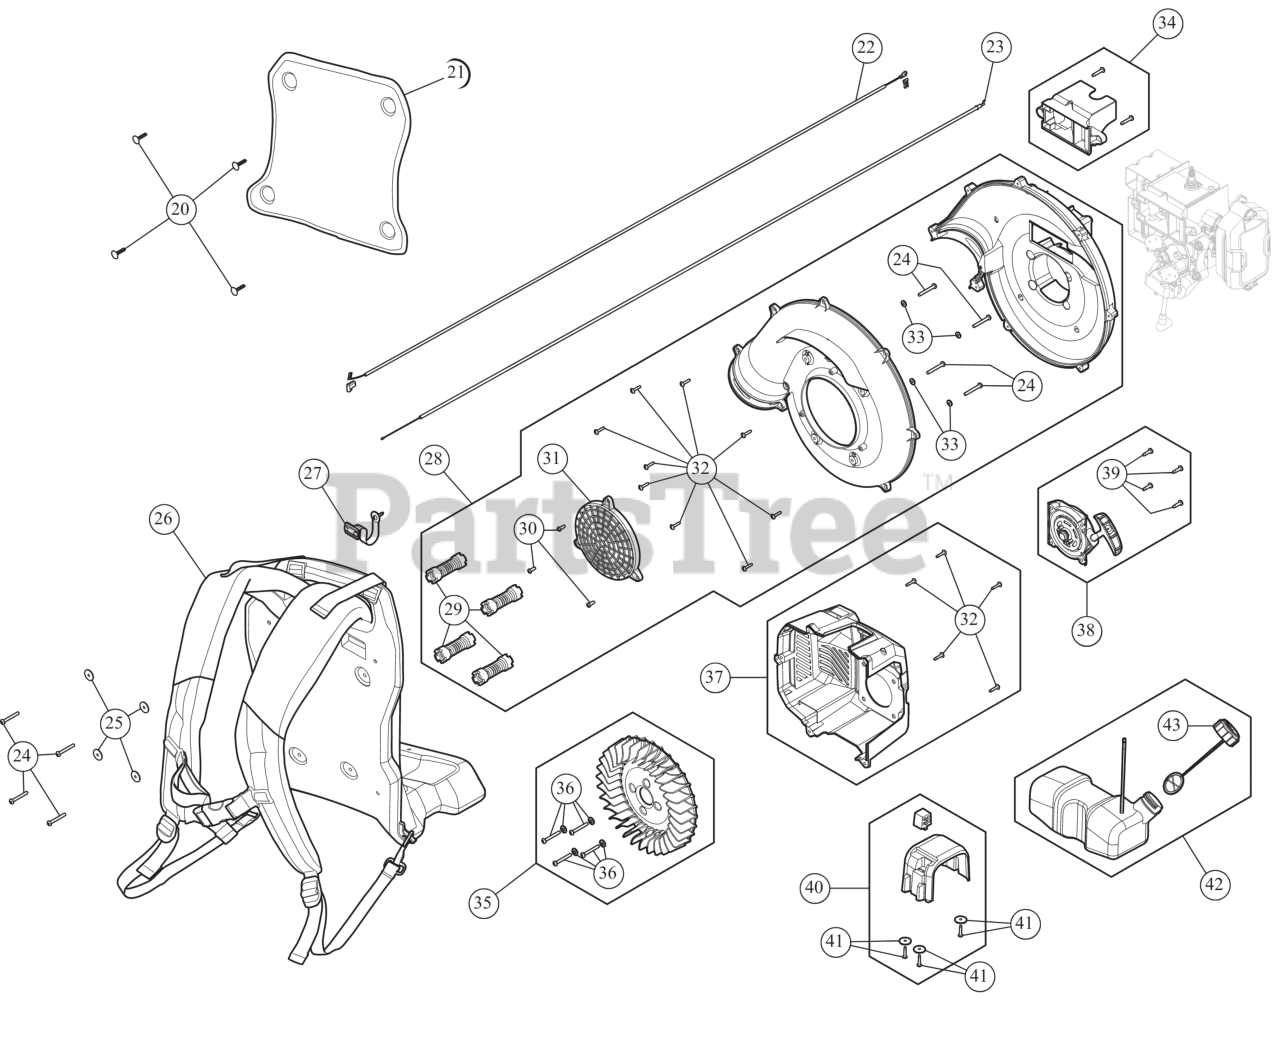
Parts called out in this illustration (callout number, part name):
20	RIVET .70X.80
21	HARNESS BACK PAD
22	WIRE LEAD
23	THROTTLE CABLE
24	SCREW
25	FLAT WASHER 0.195X0.810X0.062
26	BACKPACK HARNESS
27	TETHER STRAP
28	IMPELLER HOUSING
29	INSULATOR MOUNT
30	SCREW-10-9 x .50
31	INTAKE COVER
32	SCREW 8-16 x 3/4
33	WASH, FLAT .437X.2
34	ENGINE VENT
35	IMPELLER ASSEMBLY
36	IMPELLER HARDWARE
37	ENGINE COVER
38	STARTER
39	SCREW #
40	FUEL TANK BRACKET
41	FUEL TANK BRACKET HARDWARE
42	FUEL TANK
43	FUEL CAP
